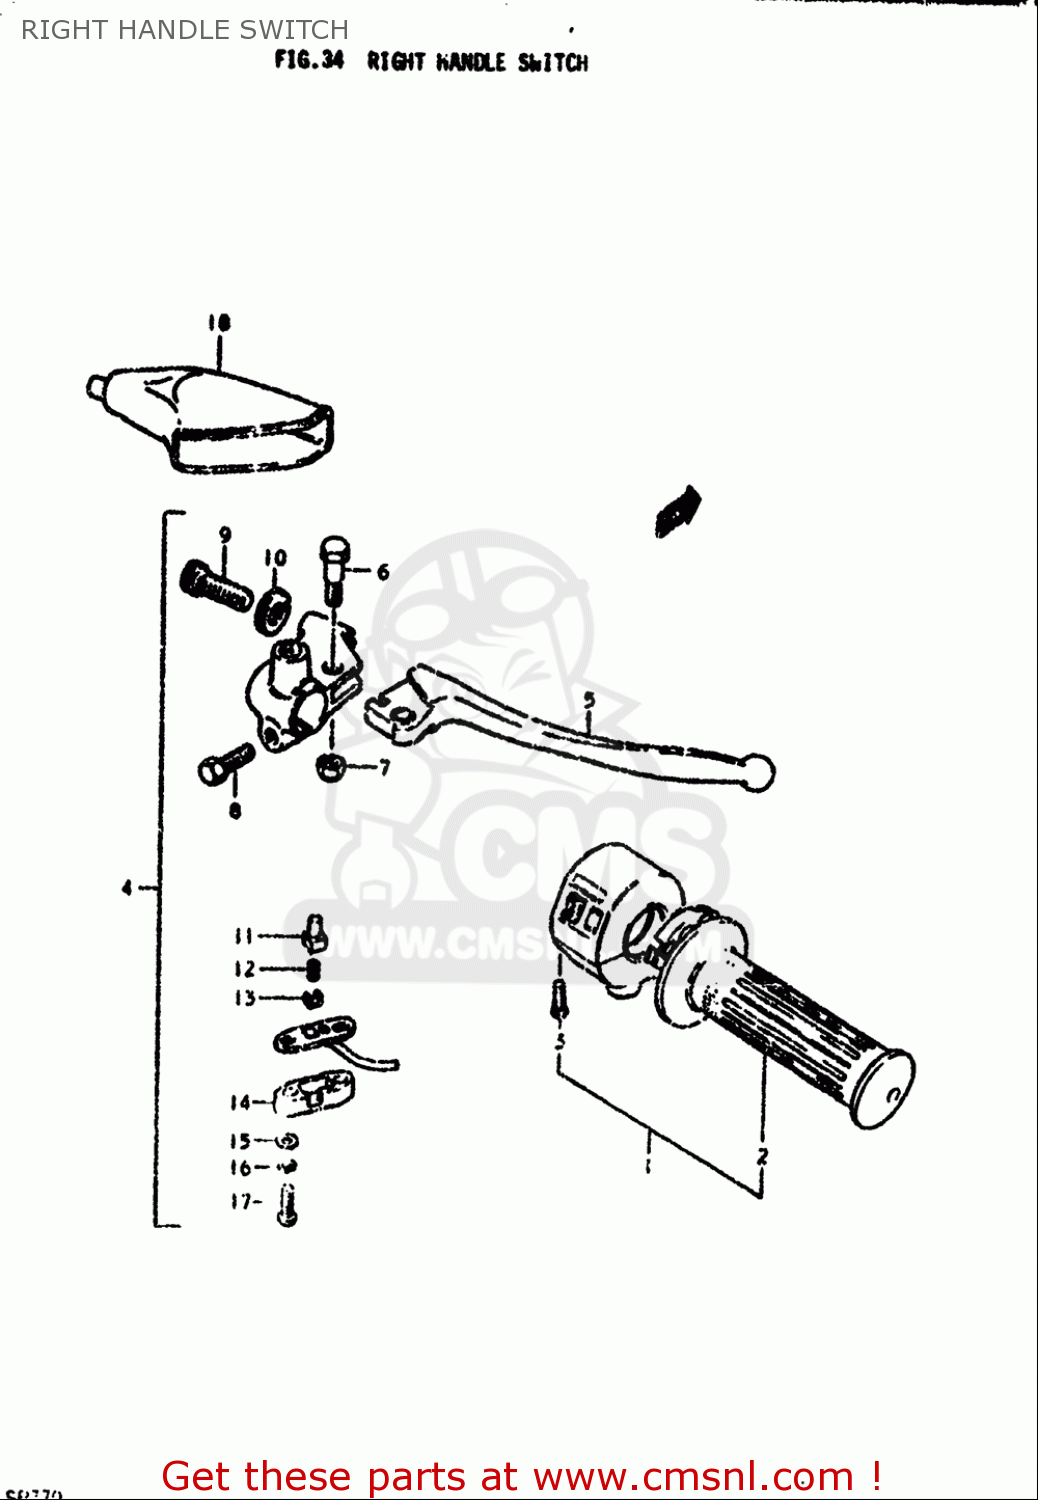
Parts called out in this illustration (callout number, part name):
1	CASE ASSEMBLY,THROTTLE
2	GRIP,THROTTLE
3	SCREW
4	BRAKE LEVER & SWITCH ASSY
5	LEVER,BRAKE
6	BOLT,LEVER PIVOT
7	NUT 6MM
8	BOLT
9	ADJUSTER,CABLE
10	NUT,CABLE ADJUSTER
11	CONTACT,SWITCH
12	CONTACT,SWITCH
13	CONTACT,SWITCH
14	COVER,FR BK TERMINAL BASE
15	WASHER
16	WASHER,LOCK
17	SCREW
18	COVER,CLUTCH LEVER
